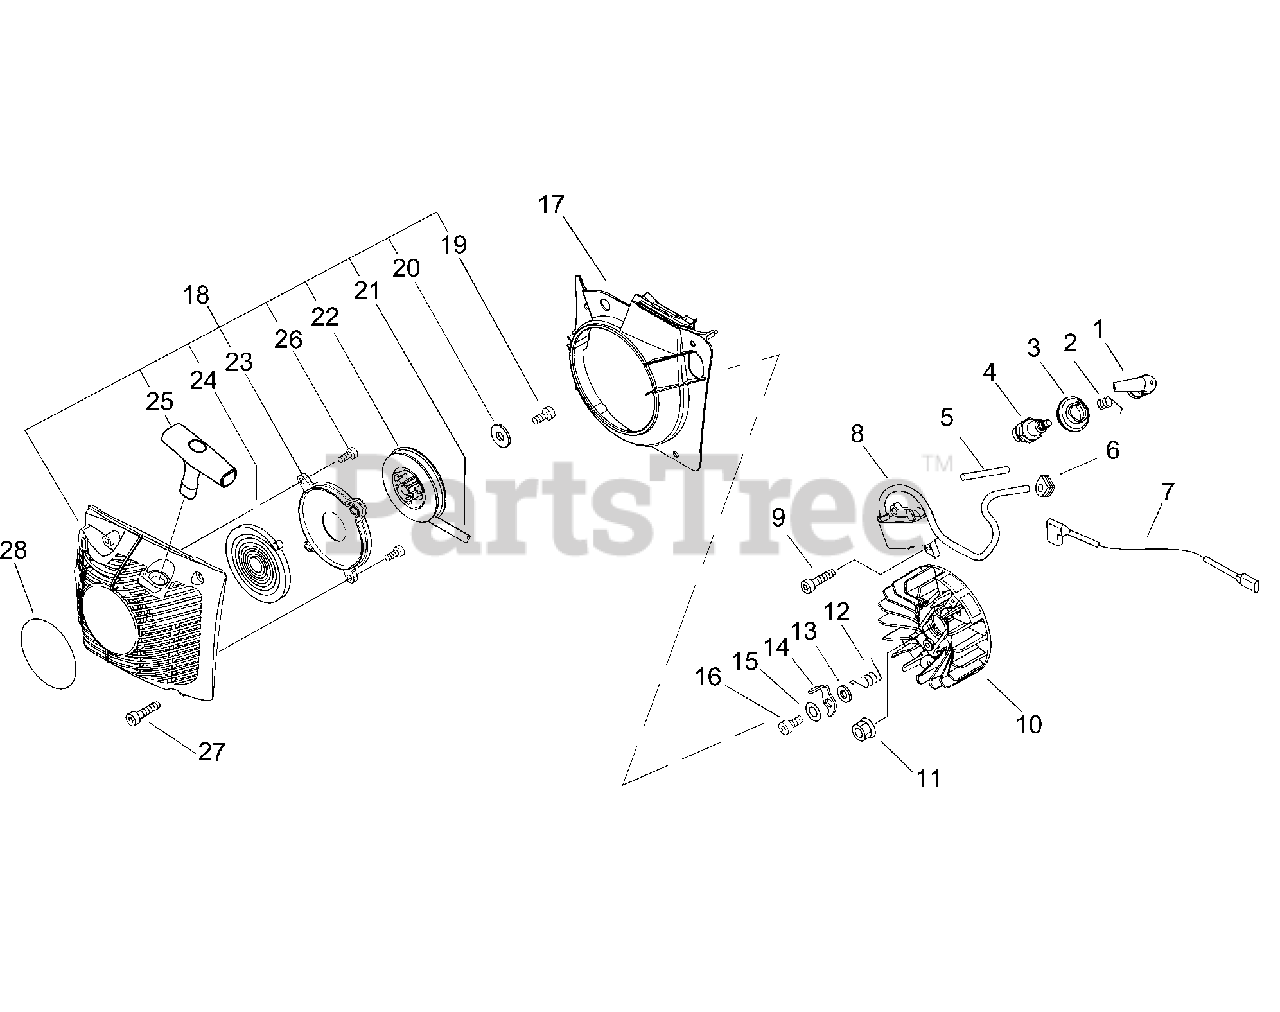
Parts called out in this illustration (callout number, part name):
1	CAP, SPARK PLUG
2	TERMINAL, SPARK PLUG
3	SEAL, SPARK PLUG
4	SPARK PLUG - BPM-8Y
5	SLEEVE, IGNITION COIL 6×7.2×70
6	GROMMET, HT CORD
7	LEAD L= 280
8	COIL, IGNITION
9	BOLT, TORX 5×16
10	FLYWHEEL
11	NUT, FLANGE M8
12	SPRING, TORSION
13	SPACER 5.2×8×2.1
14	PAWL, STARTER
15	WASHER 5.5×12×0.8
16	BOLT, TORX 5×16
17	COVER, FAN
18	STARTER ASSY, RECOIL
19	BOLT, TORX 5×10
20	WASHER 5.2×16×1.0
21	ROPE, STARTER 4×950
22	REEL, ROPE
23	PLATE, STARTER
24	SPRING, RECOIL
25	GRIP, STARTER
26	BOLT, TORX 4×12
27	BOLT, TORX 5×20
28	LABEL, ECHO
